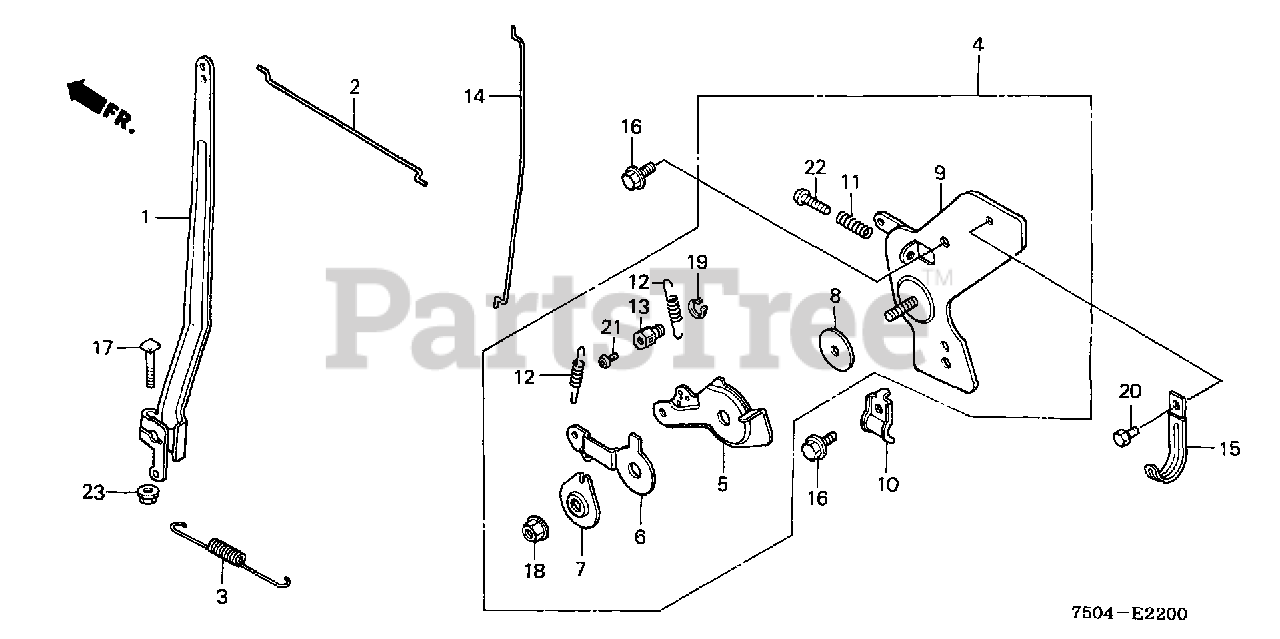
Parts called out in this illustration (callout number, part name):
1	ARM, GOVERNOR
2	ROD, GOVERNOR
3	SPRING, GOVERNOR
4	CONTROL ASSY.
5	LEVER, CONTROL
6	LEVER, CHOKE
7	WASHER, CONTROL LEVER
8	SPACER, CONTROL LEVER
9	BASE, CONTROL LEVER
10	HOLDER, CONTROL CABLE
11	SPRING, CONTROL ADJUSTING
12	SPRING, CABLE RETURN
13	HOLDER, WIRE
14	ROD, CHOKE ARM
15	CLIP C, WIRE HARNESS
16	BOLT, FLANGE (6X12) (CT200)
17	BOLT, GOVERNOR ARM
18	NUT, SELF-LOCK (6MM)
19	CIRCLIP (5MM)
20	BOLT, HEX. (5X8)
21	SCREW, PAN (4X6)
22	SCREW, PAN (5X22)
23	NUT, FLANGE (6MM)
